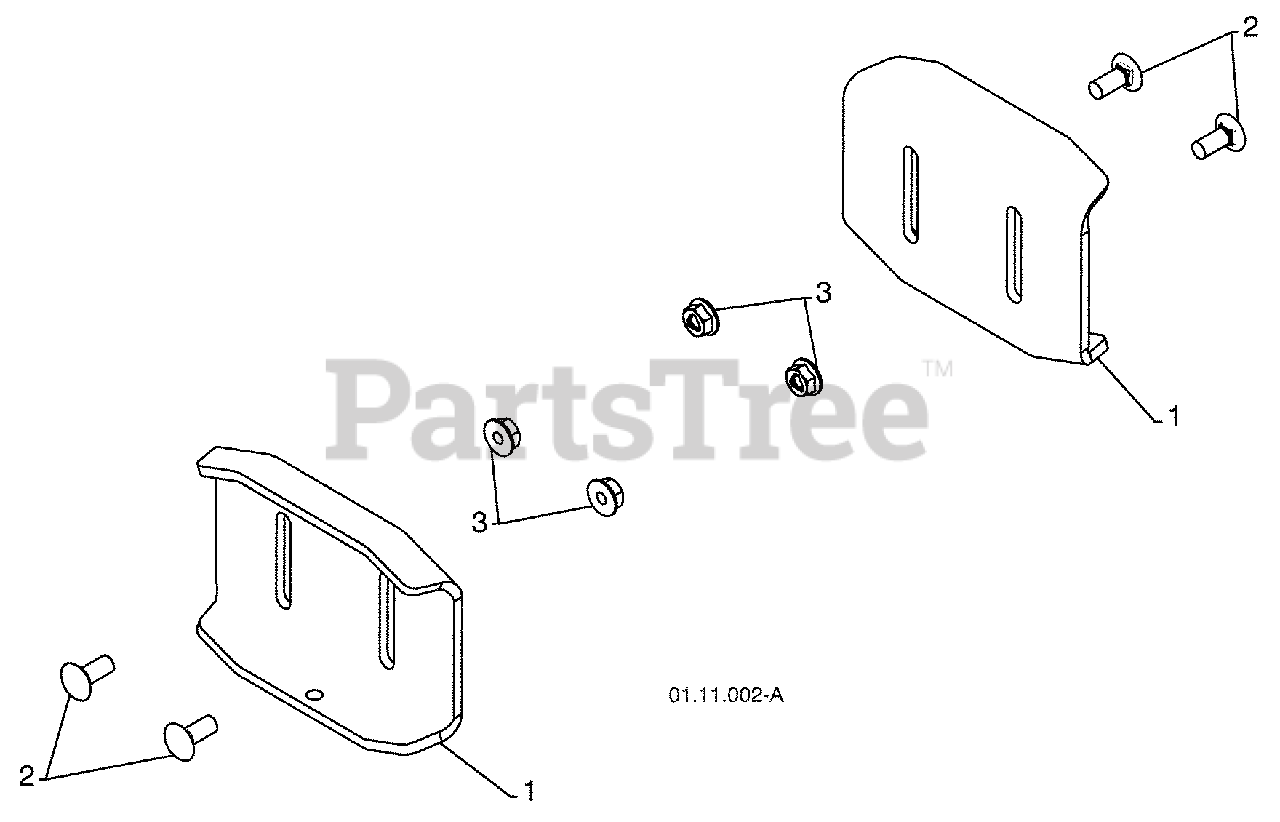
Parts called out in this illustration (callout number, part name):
1	SKID PLATE
2	CARRIAGE BOLT 5/16?18 X .750
3	NUT 5/16--18
